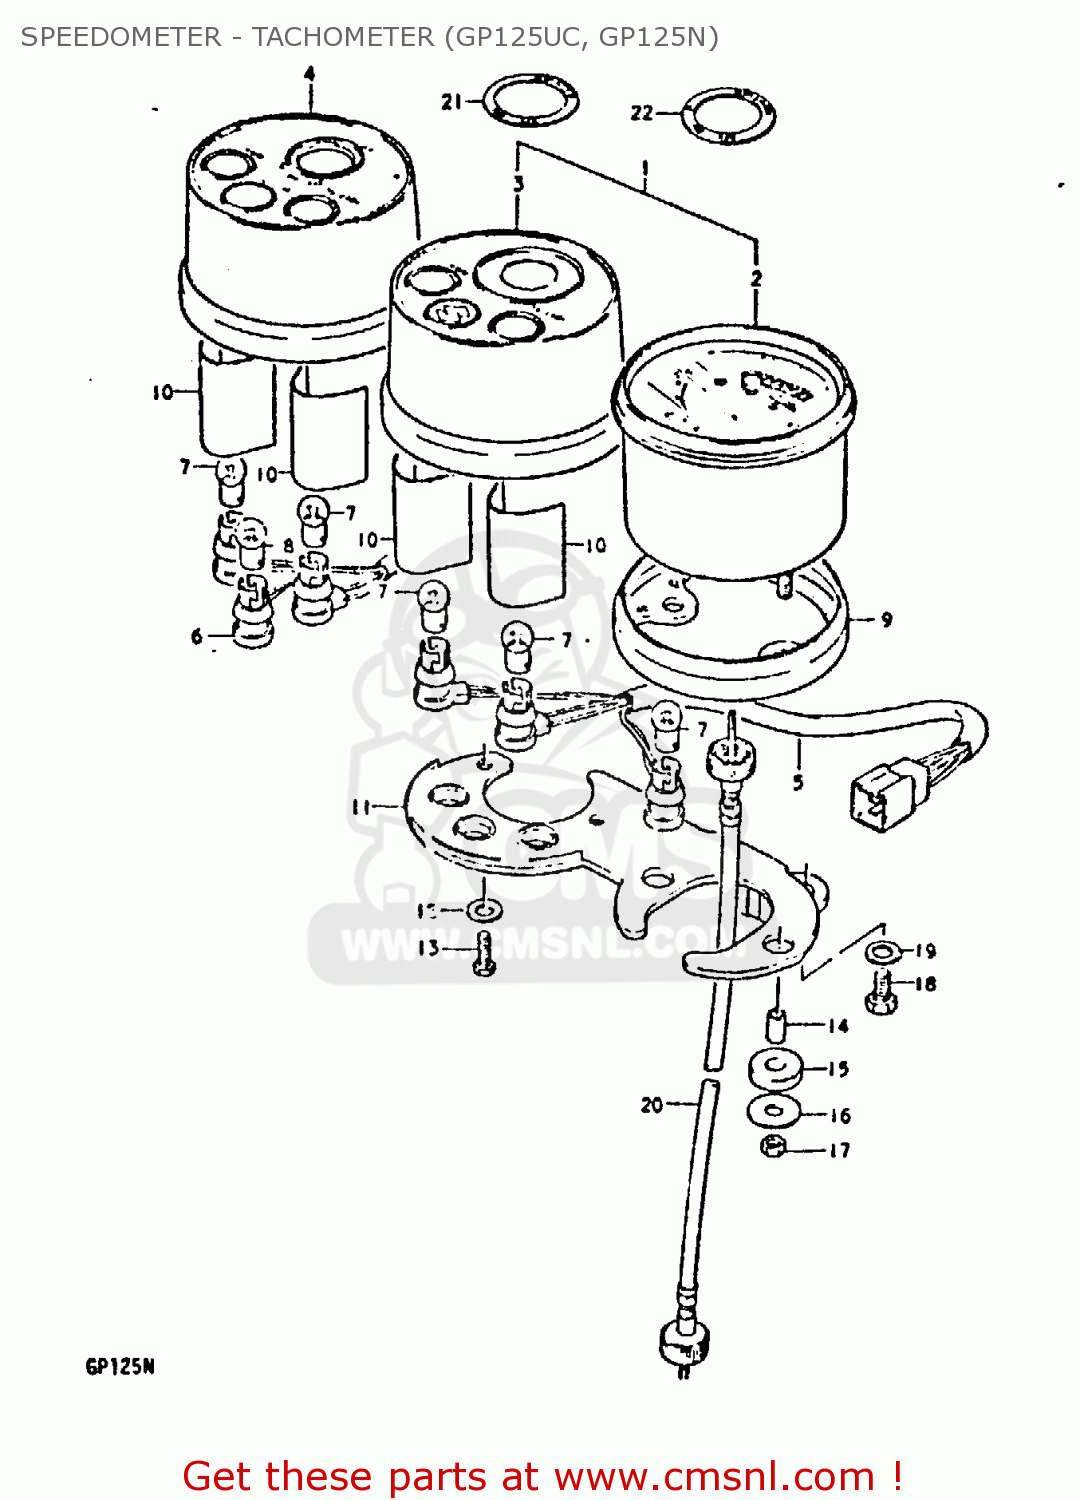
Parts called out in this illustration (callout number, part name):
3	KNOB,TRIP METER
5	SOCKET
6	BULB(6V1.7W,STANLEY,A61A)
7	BULB(6V/3W)
8	GASKET, METER
9	CASE, METER
10	BRACKET
11	CUSHION
12	SPACER
13	WASHER,METER
14	NUT
15	UNDER PLATE
16	BOLT 8X12
17	WASHER
18	CABLE ASSY, SPEEDOMETER
19	CABLE ASSY, TACHOMETER
